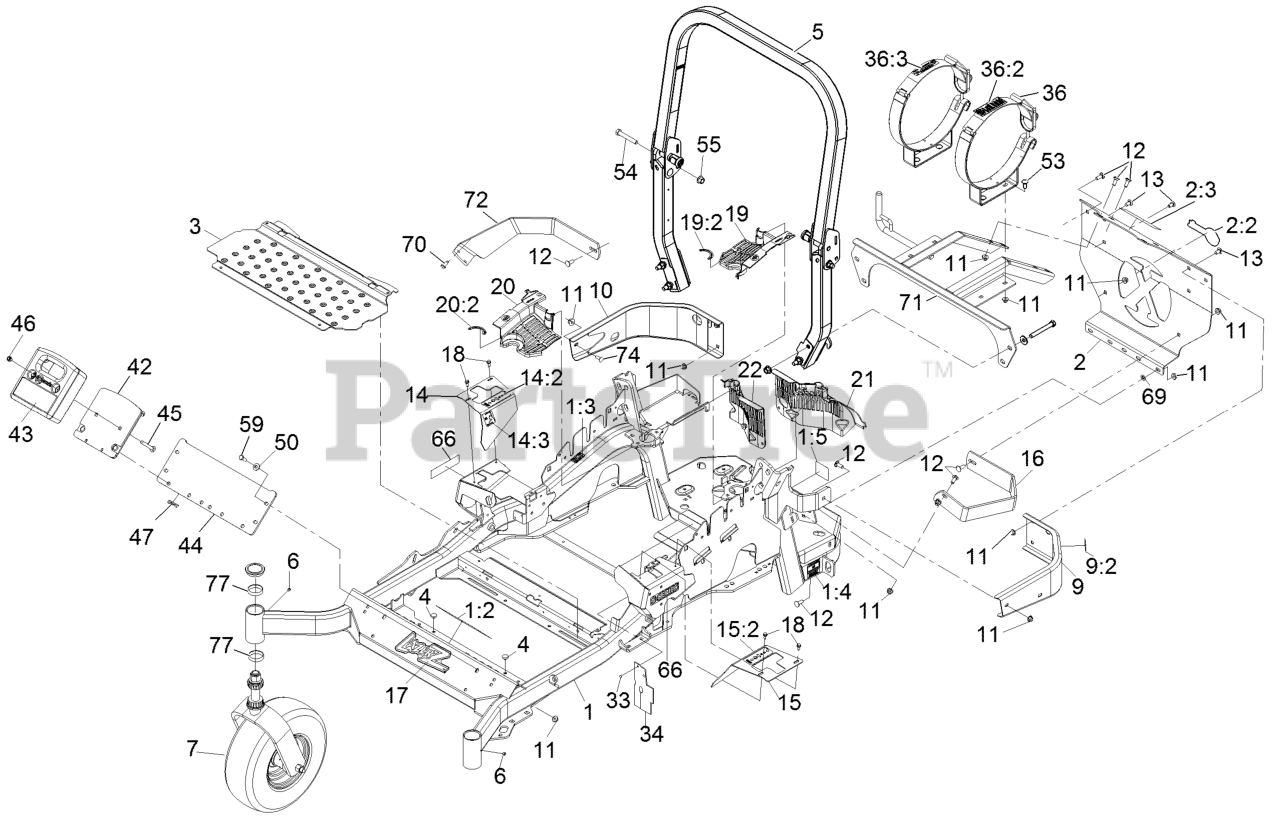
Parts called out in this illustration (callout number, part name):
1	MAINFRAME ASM
1:2	DECAL-SLOPE
1:3	DECAL-CAUTION
1:4	DECAL-BELT DRIVE
1:5	DECAL-SPARK ARRESTER
2	REAR GUARD-LP W/DECALS
2:3	DECAL-TANK REPLACEMENT
5	ROPS ASM
7	Caster Wheel Asm
9	LH BUMPER ASM
9:2	DECAL-CAUTION
10	BUMPER-RH
11	NUT-HF, NI
12	SCREW-CARR
13	SCREW-CARR
14	RH MOTION CONTROL COVER ASM
14:2	DECAL-MOTION CONTROL
14:3	DECAL-PARK BRAKE
15	LH MOTION CONTROL COVER ASM
15:2	DECAL-MOTION CONTROL
16	GUARD-MUFFLER
17	DECAL,LAZER MODEL
18	SCREW-HWH
19	LH HYDRO GUARD ASM
19:2	DECAL-HYDRO OIL
20	RH HYDRO GUARD ASM
20:2	DECAL-HYDRO OIL
21	GUARD-HYDRO, REAR (LH)
22	GUARD-HYDRO, REAR (RH)
33	RIVET-POP
34	DEFLECTOR-AIR FLOW
36	TANK BRACKET ASM (SET)
36:2	DECAL-LPG WARNING
36:3	DECAL-LPG 43.5LB TANK
42	WLD,WEIGHT MOUNT
43	WEIGHT,CAST 36LB
44	PLATE,WEIGHT ASM MOUNT
45	SCREW-CARR
46	NUT-LOCK, NI
47	PIN-HAIR
50	WASHER-BELLEVILLE
53	BOLT-CARR
54	SCREW-HH
55	Nut-Lock 1/2-13
59	SCREW-HH
66	DECAL-S-SERIES
69	NUT-PUSH
70	Screw-HWH 5/16-18 X 3/4 Tf
71	SUPPORT-TANK
72	STRAP-GUARD
74	BOLT-CARR
77	CUP-BEARING
